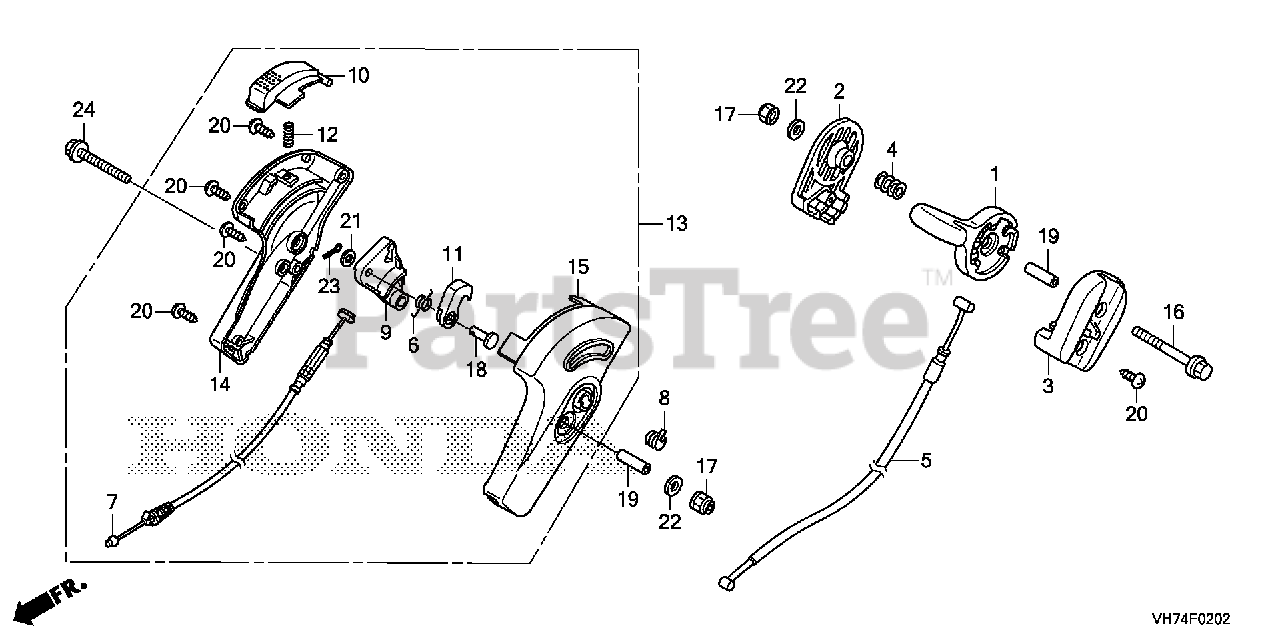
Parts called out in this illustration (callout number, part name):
1	LEVER, THROTTLE
2	CASE, R. THROTTLE LEVER
3	CASE, L. THROTTLE LEVER
4	SPRING, THROTTLE LEVER
5	CABLE, THROTTLE
6	SPRING, LOCK LEVER RETURN
7	CABLE, ROTO-STOP
8	SPRING, R. STOP RETURN
9	ARM, ROTO-STOP CABLE
10	KNOB, PUSH
11	LEVER, LOCK
12	SPRING, LEVER RETURN
13	CONTROL ASSY., ROTO-STOP
14	CASE, ROTO-STOP (R)
15	CASE, ROTO-STOP (L)
16	BOLT, FLANGE (6X65)
17	NUT, NYLON LOCK (6MM)
18	PIN, CLUTCH LEVER
19	COLLAR, THROTTLE
20	SCREW, TAPPING (4X12)
21	WASHER, PLAIN (6MM)
22	WASHER, PLAIN (6MM)
23	PIN, LOCK (6MM)
24	BOLT, FLANGE (6X65)
